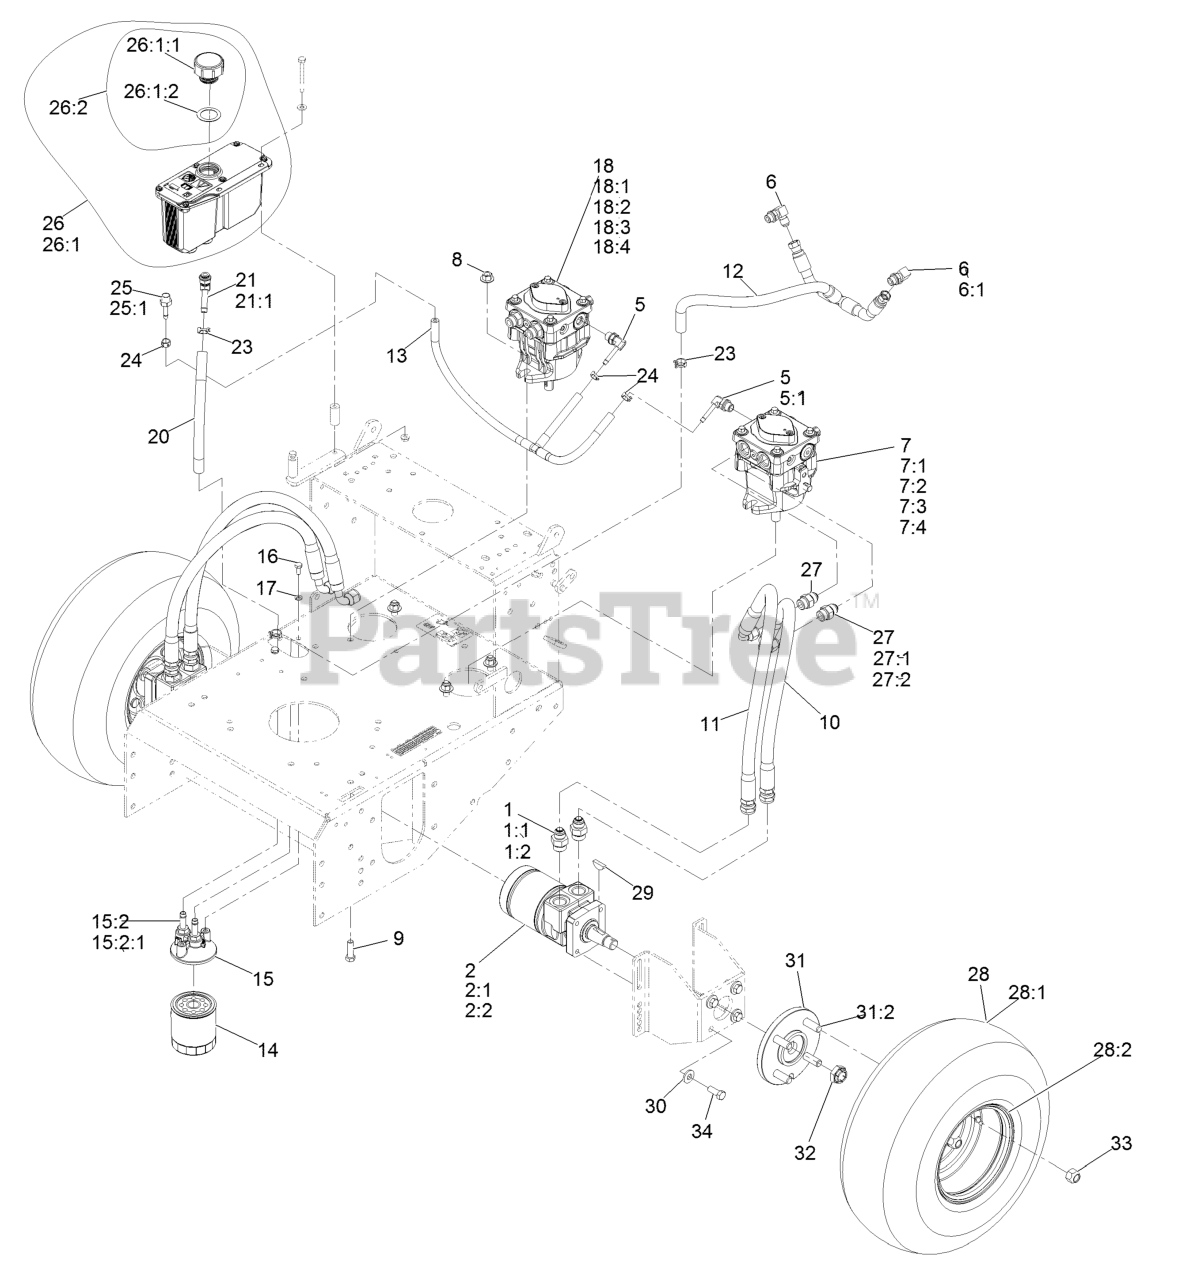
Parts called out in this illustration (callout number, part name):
1	FITTING-STRAIGHT
1:1	O-RING
2	HYD MOTOR ASM
2:1	SEAL KIT
2:2	BEARING AND SEAL KIT
5	ELBOW-90 DEG
5:1	O-RING
6	FITTING-ELBOW, 90 DEG
7	LH HYD PUMP ASM
7:1	INPUT SHAFT KIT
7:2	BEARING-THRUST
7:3	CYLINDER BLOCK KIT
7:4	SEAL OVERHAUL KIT
8	NUT-FLANGE
9	SCREW-HH
10	HYD HOSE ASM
11	HYD HOSE ASM
12	CHARGE HOSE ASM
13	CASE DRAIN HOSE ASM
14	ELEMENT-FILTER, WINTER
14	FILTER-25 MICRON, BI-DIRE
15	FILTER HEAD ASM
15:2	ADAPTER-STRAIGHT
15:2:1	O-RING
16	SCREW-HH
17	WASHER-LOCK
18	RH HYD PUMP ASM
18:1	INPUT SHAFT KIT
18:2	BEARING-THRUST
18:3	CYLINDER BLOCK KIT
18:4	SEAL OVERHAUL KIT
20	HOSE-CHARGE
21	FITTING-BARBED, 45 DEG
21:1	O-RING
23	CLAMP-HOSE
24	CLAMP-HOSE
25	ADAPTER-STRAIGHT
25:1	O-RING
26:1	Reservoir-HYD
26:1:1	Cap-Reservoir, HYD
26:1:2	GASKET-CAP
26:2	DECAL-WARNING
27	FITTING-STRAIGHT
28	WHEEL AND TIRE ASM
28:1	TIRE-TURFMASTER
28:2	RIM-WHEEL
29	KEY-WOODRUFF
30	WASHER-BELLEVILLE
31	WHEEL HUB ASM
31:2	STUD-WHEEL
32	NUT-LOCK
33	NUT-LUG
34	SCREW-HH
